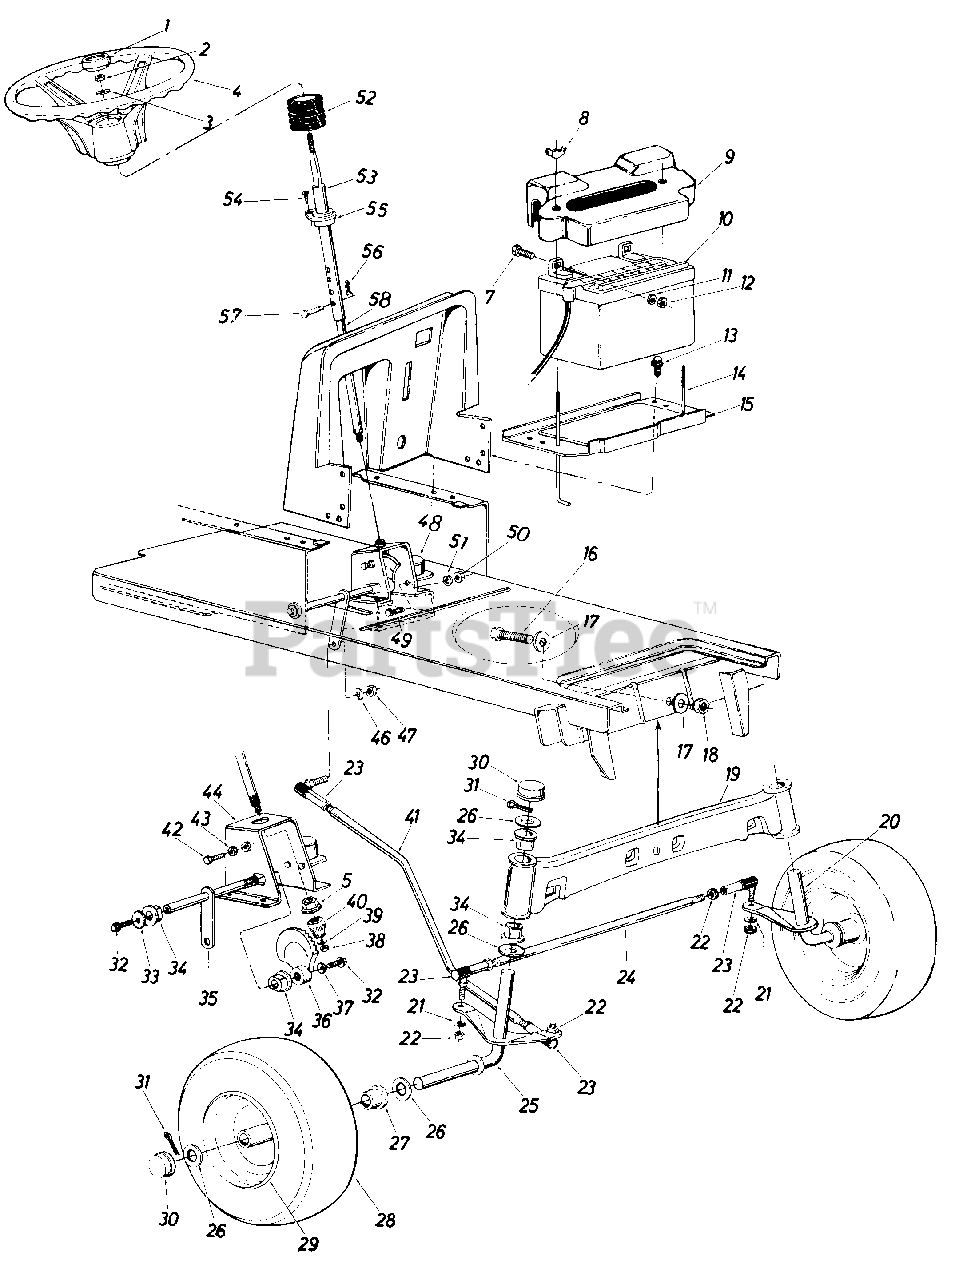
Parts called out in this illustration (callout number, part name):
1	Steering Wheel Cap
2	Hex Cent. L-Nut 5/16-18 Thd.
3	Bell-Wash. 5/16" I.D. x .87" O.D. x .060
4	Steering Wheel
5	Plastic Hex Brg. 5/8" I.D.
7	Hex Scr. 1/4-20 x .62" Lg.
8	Wing Nut Plastic 1/4-20 Thd.
9	Battery Cover
10	12-V Battery
11	L-Wash. 1/4" Scr.
12	Hex Nut 1/4-20 Thd.
13	Hex Thd. Rolling Scr. 1/4-20 x .50" Lg.
14	Battery Hold Down Rod
15	Battery Plate
16	Hex Scr. 5/8-18 x 2.50" Lg.
17	Flat Wash. .66" I.D. x 2.25" O.D. x .17
18	Hex Cent. L-Nut 5/8-18 Thd.
19	Front Pivot Bar Ass'y.
20	Front Axle Ass'y. L.H.
21	L-Wash. 3/8 Scr.
22	Hex Nut 3/8-24 Thd.
23	Ball Joint Ass'y.
24	Tie Rod
25	Front Axle Ass'y. R.H.
26	Fl-Wash. .780 I.D. x 1.59 O.D.
27	Flange Bearing
28	Front Wheel Ass'y. Comp.
29	Front Wheel Rim Only
30	Dust Cover
31	Cotter Pin 5132" Dia. x 1.00"
32	Hex Scr. 3/8-24 x .75" Lg. Grade 5
33	Fl-Wash. 3/8 I.D.. x 1.25 O.D. x .090
34	Flange Double " D" Brg. .753 I.D.
35	Steering Arm Shaft Ass'y.
36	Side Gear Steering
37	Bell-Wash. 3/8" I.D.
38	Hex Cent. L-Nut 5/16-24 Thd.
39	Fl-Wash. 5/16" I.D. x .62 O.D. x .059
40	Pinion Gear Steering
41	Drag Link
42	Hex Nylon Scr. 3/8-16 x 1.25" Lg.
43	Hex Nut 3/8-16 Thd.
44	Steering Gear Sup. Ass'y.
46	L-Wash. 3/8 Scr.
47	Hex Nut 3/8-24 Thd.
48	Solenoid
49	Hex Scr. 1/4-20 x .62" Lg.
50	Hex Nut 1/4-20 Thd.
51	L-Wash. 1/4" Scr.
52	Steering Bellow
53	Upper Steering Shaft
54	Oval Hd. Cr.-Sunk Scr. #10 x 5/8" Lg.
55	Fl-Bearing .89" I.D. x 1.36" O.D.
56	Hairpin Cotter
57	Clevis Pin
58	Lower Steering Shaft
